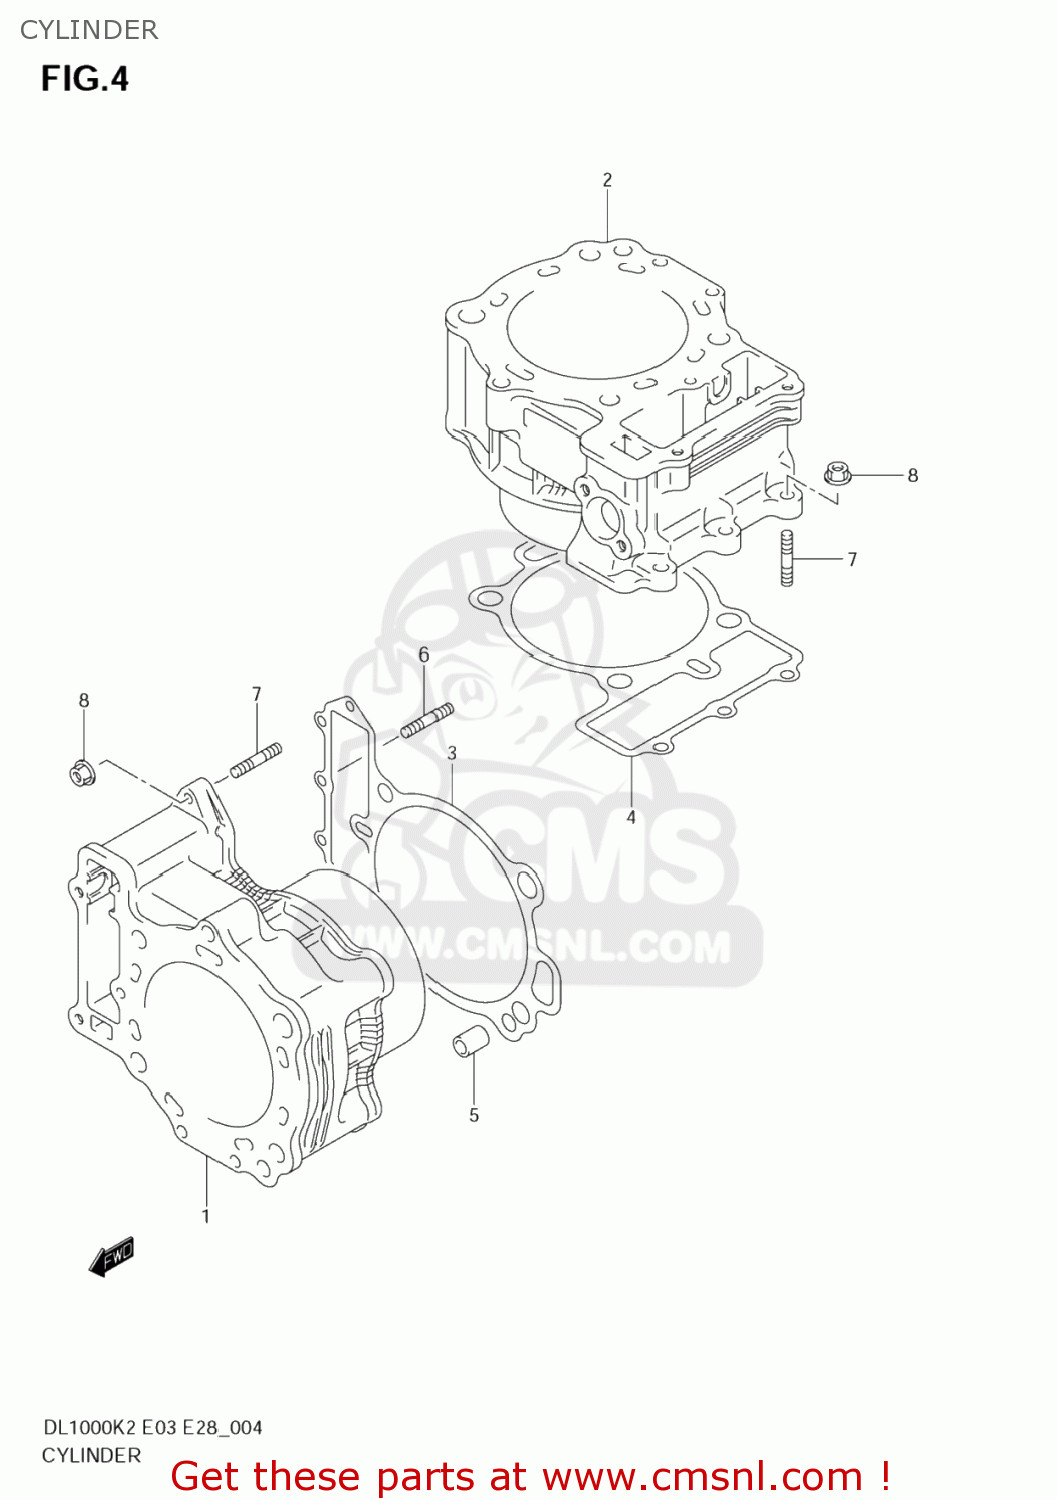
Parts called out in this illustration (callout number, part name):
1	CYLINDER,FR
2	CYLINDER,RR
3	GASKET,CYLINDER FR (NAS)
4	GASKET,CYLINDER RR (NAS)
5	PIN
6	STUD BOLT (L:20)
7	STUD,M6X1X32
8	NUT
